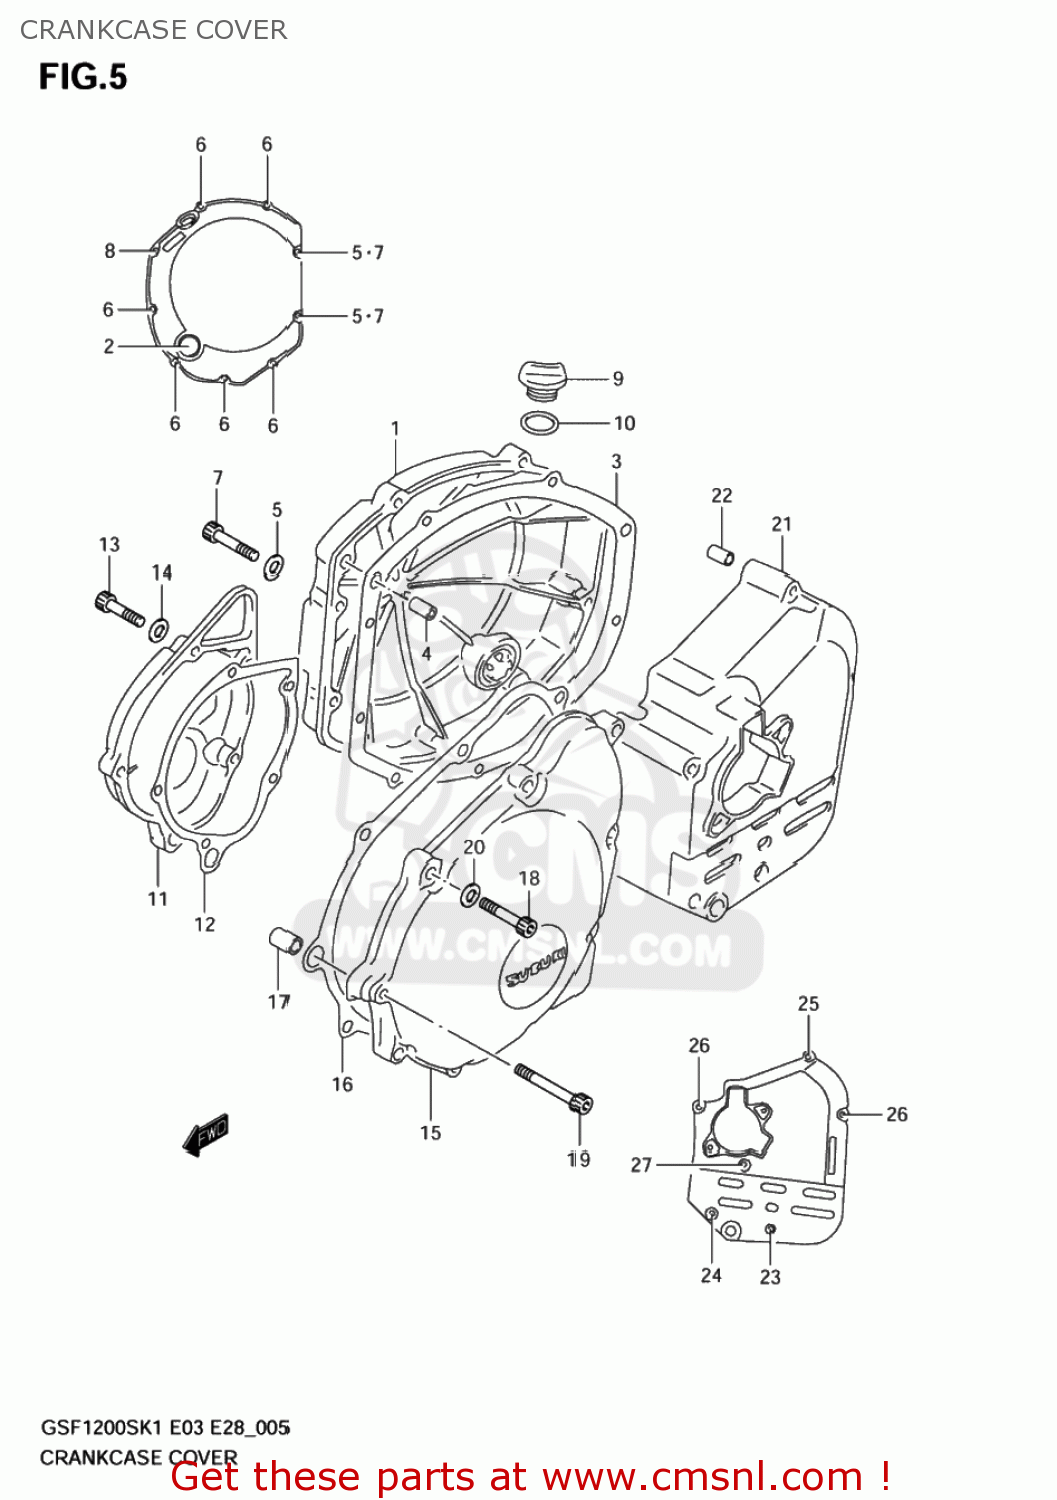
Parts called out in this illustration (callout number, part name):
1	COVER,CLUTCH
2	LENS,OIL LEVEL CHECK
3	GASKET,CL COVER (NAS)
4	PIN
5	GASKET(5.8X13X1.2) (NAS)
6	BOLT(6X25)
7	BOLT
8	BOLT
9	PLUG
10	O RING(D:3.1,ID:16.8)
11	COVER,SIGNAL GENERATOR
12	GASKET,SIGNAL GEN COVER (NAS)
13	BOLT(6X22)
14	GASKET(5.8X13X1.2) (NAS)
15	COVER,STARTER GEAR
16	GASKET,STARTER GEAR COVER (NAS)
17	PIN(8.4X11X20)
18	BOLT(6X25)
19	BOLT
20	GASKET(5.8X13X1.2) (NAS)
21	COVER,ENGINE SPROCKET
22	PIN
23	BOLT
24	BOLT
25	BOLT
26	BOLT
27	BOLT
